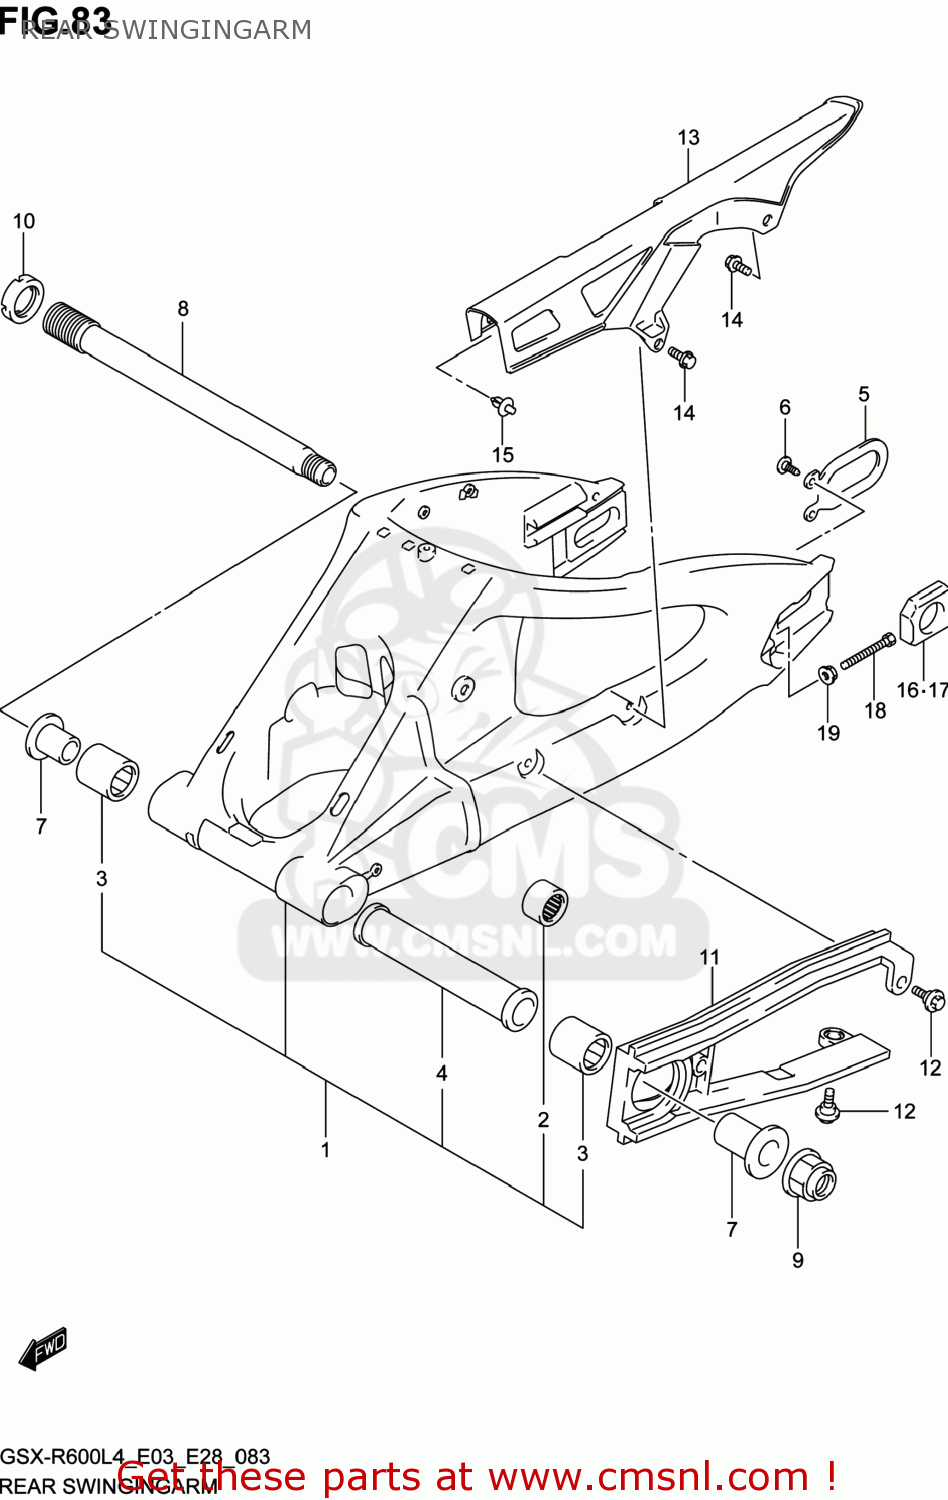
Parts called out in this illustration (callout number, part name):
1	SWINGINGARM ASSY,RR
2	BEARING(20X27X30)
3	BEARING(27X35X35)
4	SPACER,RR SWG PVT CTR
5	PLATE,RR SWING ARM BRKT
6	SCREW(6X12)
7	SPACER,RR SWGARM PIVOT BEARING
8	SHAFT,RR SWINGINGARM PIVOT
9	NUT
10	NUT,RR SWGARM PIVOT BOLT
11	BUFFER,CHAIN TOUCH DEFENSE
12	BOLT(6X17.8)
13	CASE,CHAIN
14	BOLT(6X12)
15	CLIP(BLACK)
16	ADJUSTER,CHAIN,R
17	ADJUSTER,CHAIN,L
18	BOLT(8X50)
19	NUT
